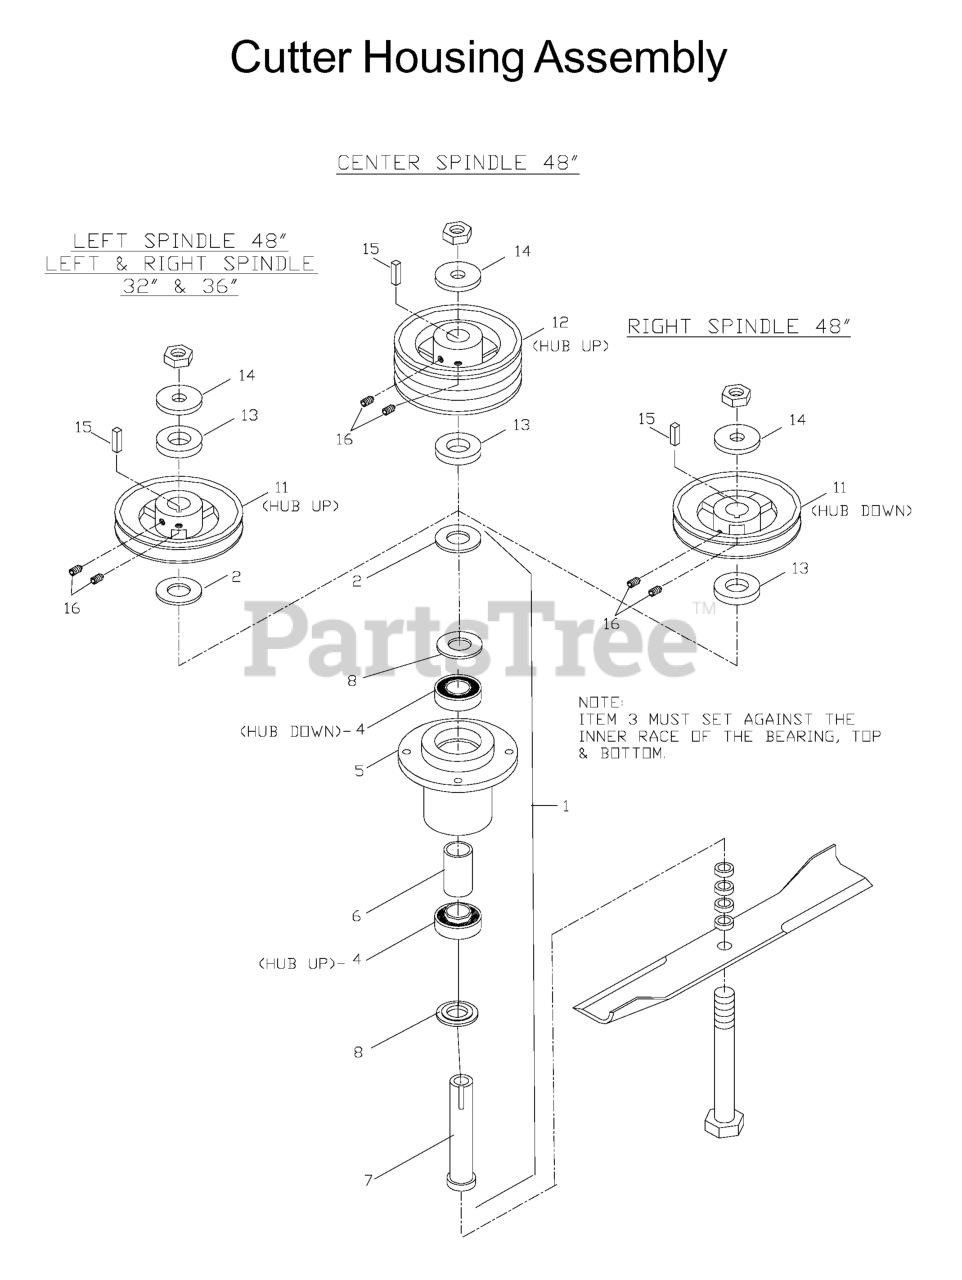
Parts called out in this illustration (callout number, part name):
1	HOUSING ASM
2	MACHINERY BUSHING 10 GA.
4	BEARING
7	SPINDLE SHAFT
8	COMBO SPACER
11	PULLEY W/SETSCREWS
12	PULLEY, DOUBLE W/SETS
14	WASHER, SUPPORT
15	KEY 1/4 SQ X 1 1/8
16	SET SCREW 5/16 NYLOC
